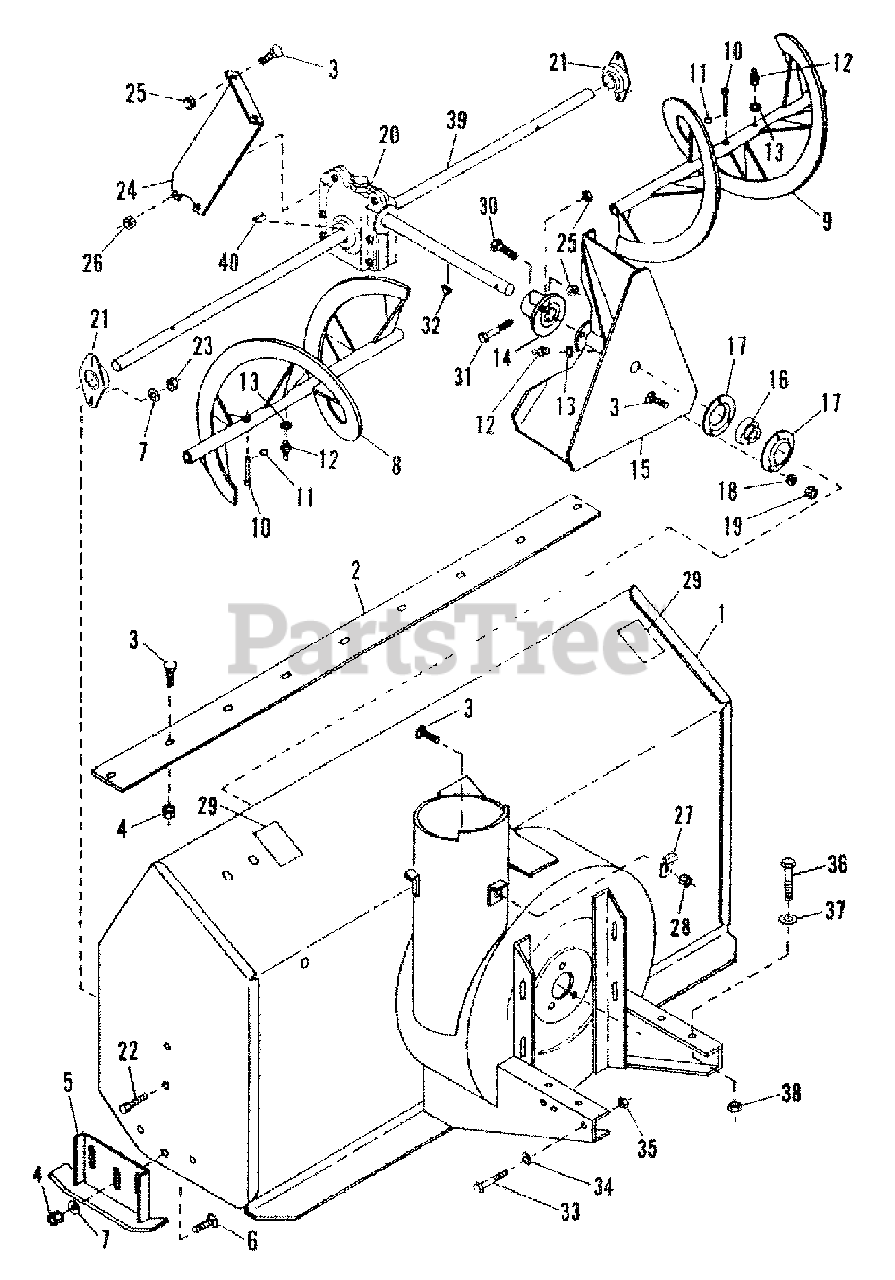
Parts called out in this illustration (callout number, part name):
1	Header Housing
2	Scraper Blade
3	Bolt, 5/16-18 x 3/4 Carriage
4	Nut and lockwasher Assy 5/16-18
5	Skid Shoe
6	Bolt, 5/16-18 x 1" Carriage
7	Washer, 3/8 x 7/8 x .083
8	Auger Assembly Left Hand
9	Auger Assembly Right Hand
10	Shear Pin and Clip
11	Spring Clip
12	Grease Fitting
13	Washer, 17/32 x 5/8 x .049
14	Fan Drive Plate
15	Thower Fan
16	Bearing
17	Flangette
18	Lockwasher 5/16 Medium
19	Nut, 5/16-18 Hex
20	Worm Drive Gearbox Assy
21	Bearing Assy
22	Bolt, 3/8-16 x 3/4 Hex Hd
23	Nylock Nut, 3/8-16 Hex
24	Gearbox Support Bracket
25	Lock Nut, 5/16-18
26	Nut, Metric MB x 1.25
27	Stack Anchor
28	Nylock Nut, 5/16-18
29	Danger Decal
30	Shear Bolt, 5/16-18 x 3/4 & Nut
31	Bolt, 5/16-18 x 2" Hex
32	Key - #15 Woodruff
33	Bolt, 3/8-16 x 2 1/4" Hex Hd.
34	Washer, 13/32 x 3/16 x .065 Flat
35	Nut, 3/8-16 Hex Lock
36	Bolt, 1/2-13 x 2 1/4" Hex Hd.
37	Washer, 17/32 x 1 1/16 x .095 Flat
38	Nut, 1/2-13 Hex Lock
39	Auger Shaft
40	Key - #91 Woodruff
